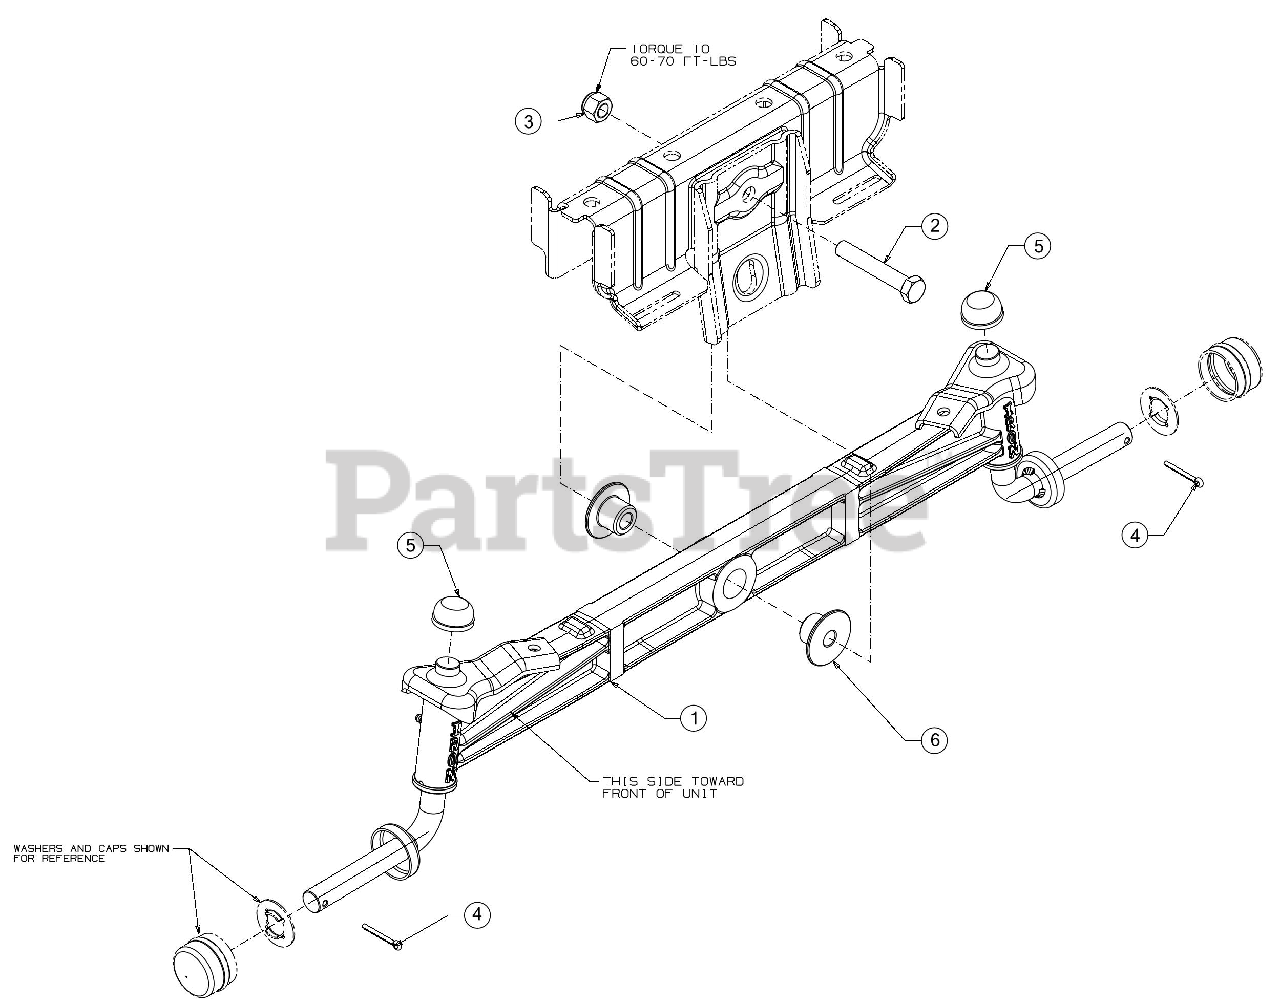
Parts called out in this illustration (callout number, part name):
1	FRONT AXLE ASSEMBLY
2	HEX SCREW 1/2-13 X 3.00
3	HEX LOCK NUT NYLON
4	COTTER PIN-5/32 DIA
6	SHOULDER SPACER
